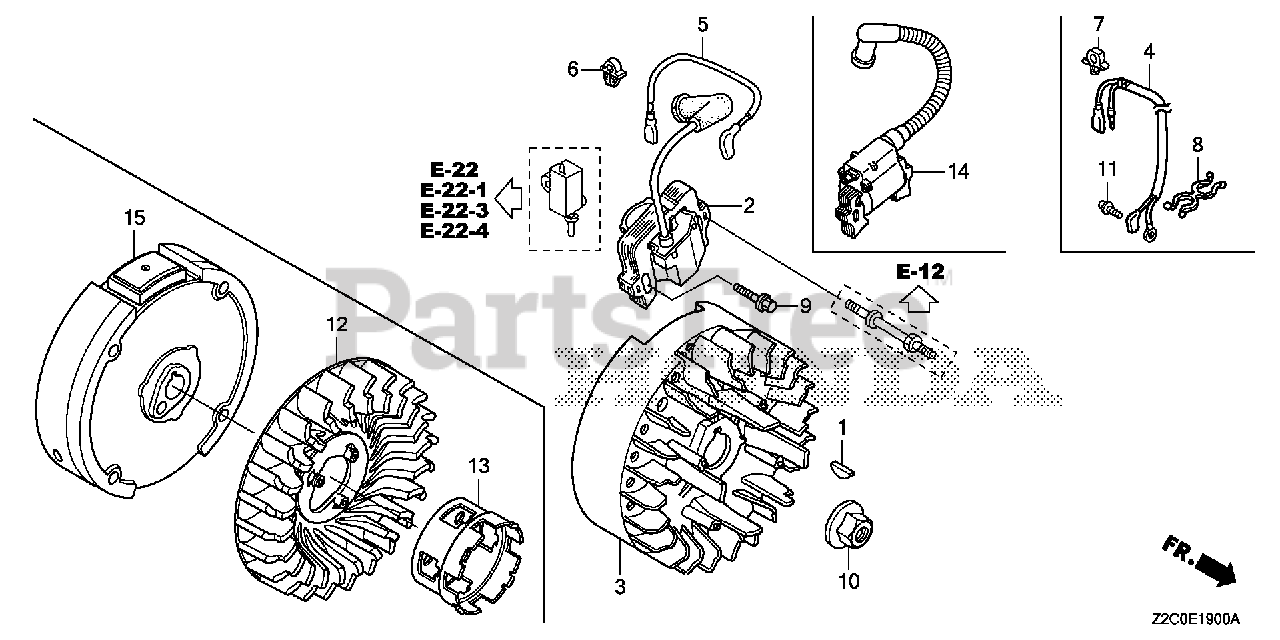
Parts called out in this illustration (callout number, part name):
1	KEY, SPECIAL WOODRUFF (25X18)
9	BOLT, FLANGE (6X23)
10	NUT, SPECIAL (14MM)
12	FAN, COOLING
13	PULLEY, STARTER
14	COIL ASSY., IGNITION (TOYO)
14	COIL ASSY., IGNITION (PHELON)
15	FLYWHEEL
